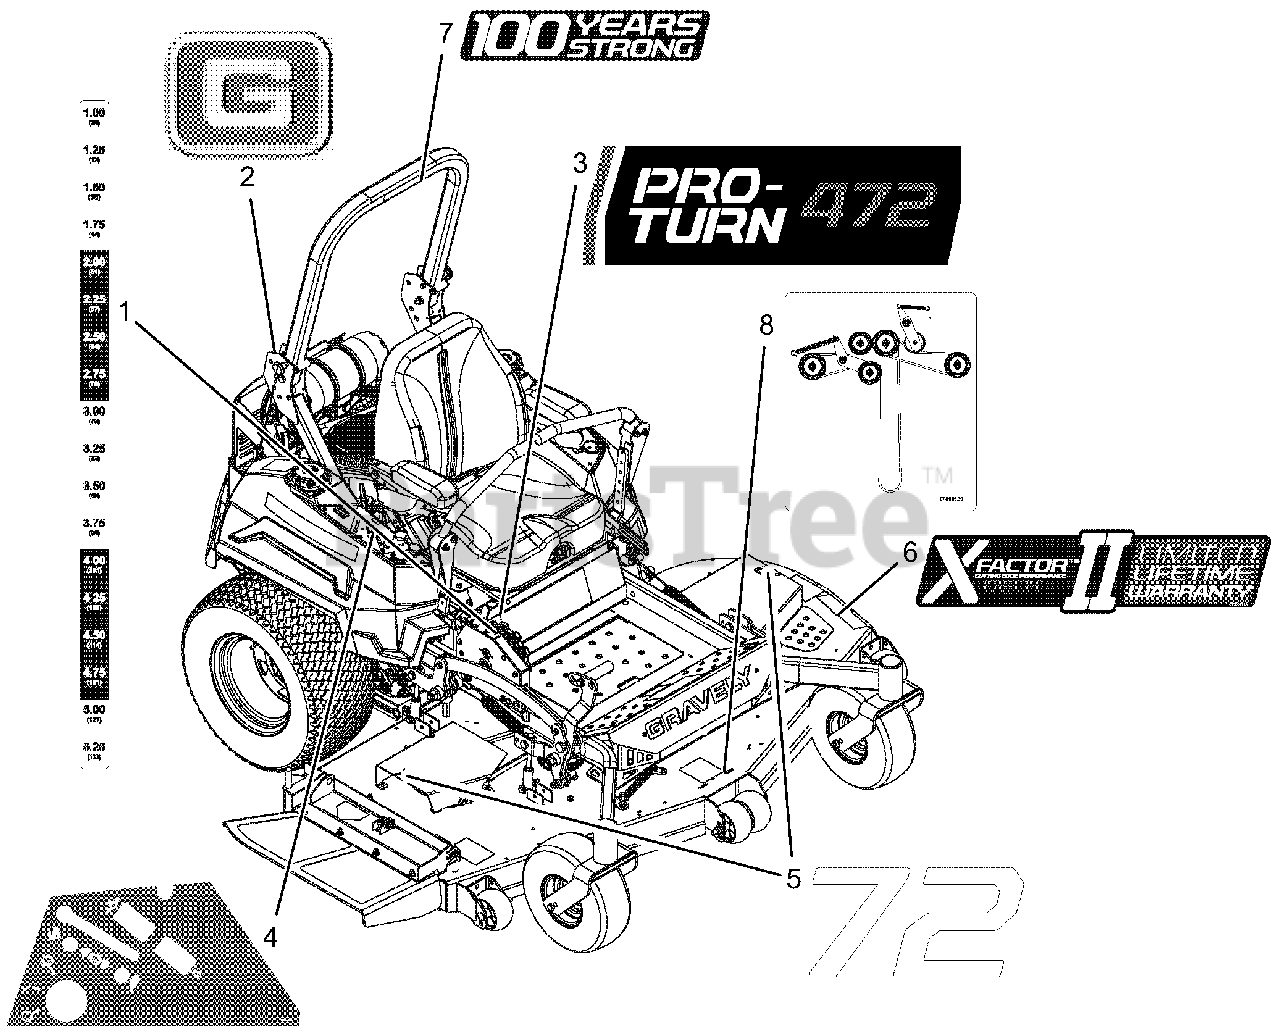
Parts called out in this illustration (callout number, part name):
1	DECAL, PT400 HEIGHT OF CUT
2	DECAL, GRAVELY BRAND
3	DECAL, PRO-TURN 472
4	DECAL, EFI CONTROL PANEL
5	DECAL, 72"
6	DECAL, X-FACTOR DECK
7	DECAL, GRAVELY 100 YR
8	DCL,BELT ROUTE-RH BK-SIDE IDLR
